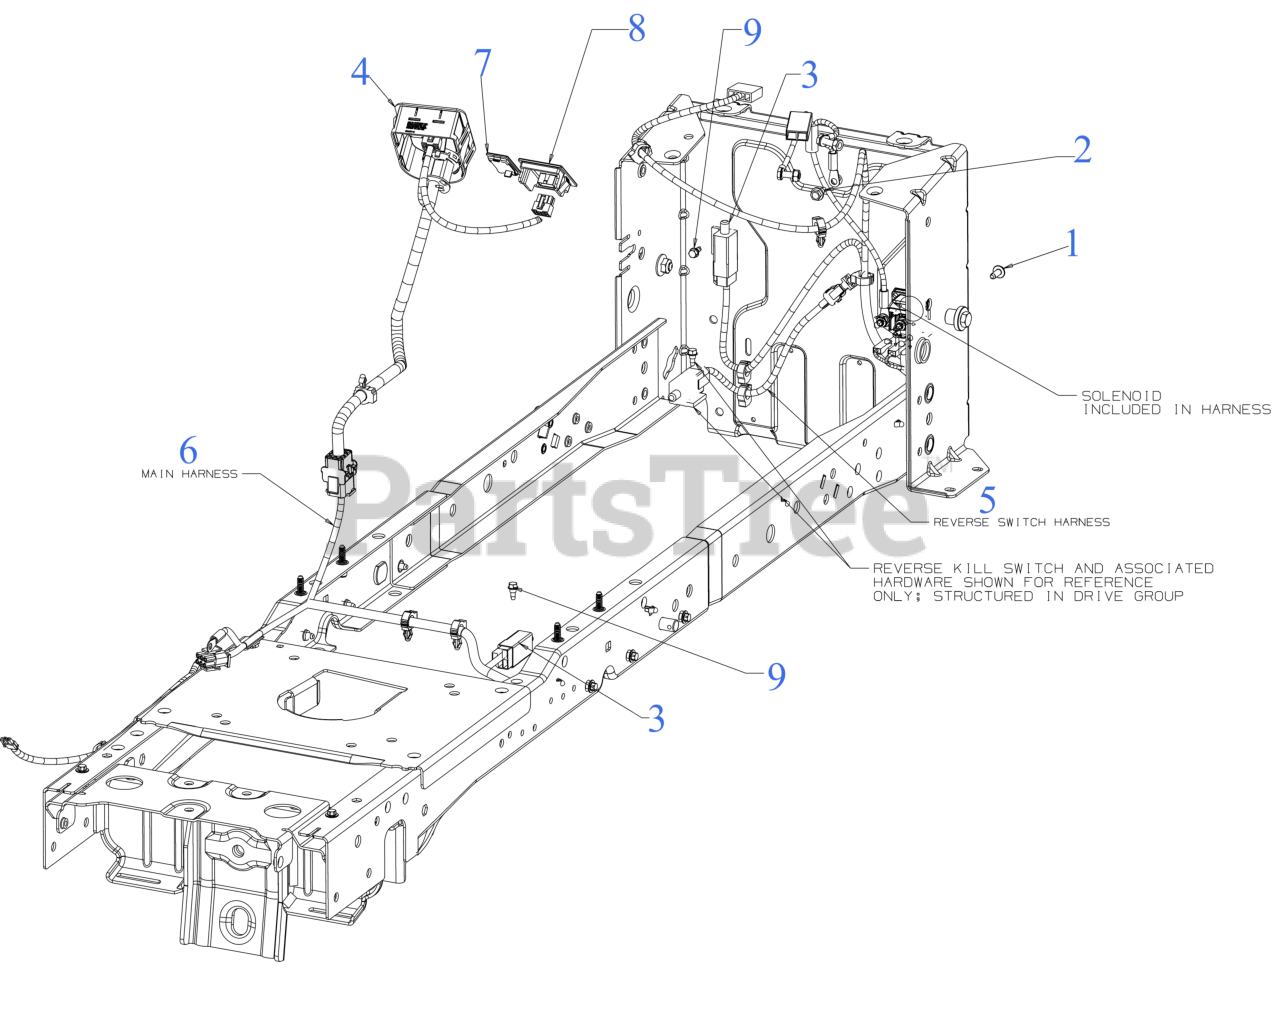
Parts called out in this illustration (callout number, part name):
1	SCREW M6-1 x .625
2	SCREW 1/4-20X.625
3	INTERLOCK SWITCH (NO/NC)
4	IGNITION MODULE SWITCH RMC (MAN PTO BLK)
5	REVERSE HARNESS
6	HARNESS (MPTO/RMC/HRMTR/DC)
6	12V SOLENOID
8	DASH HOUR METER PLUG
9	SHOULDER SCREW
